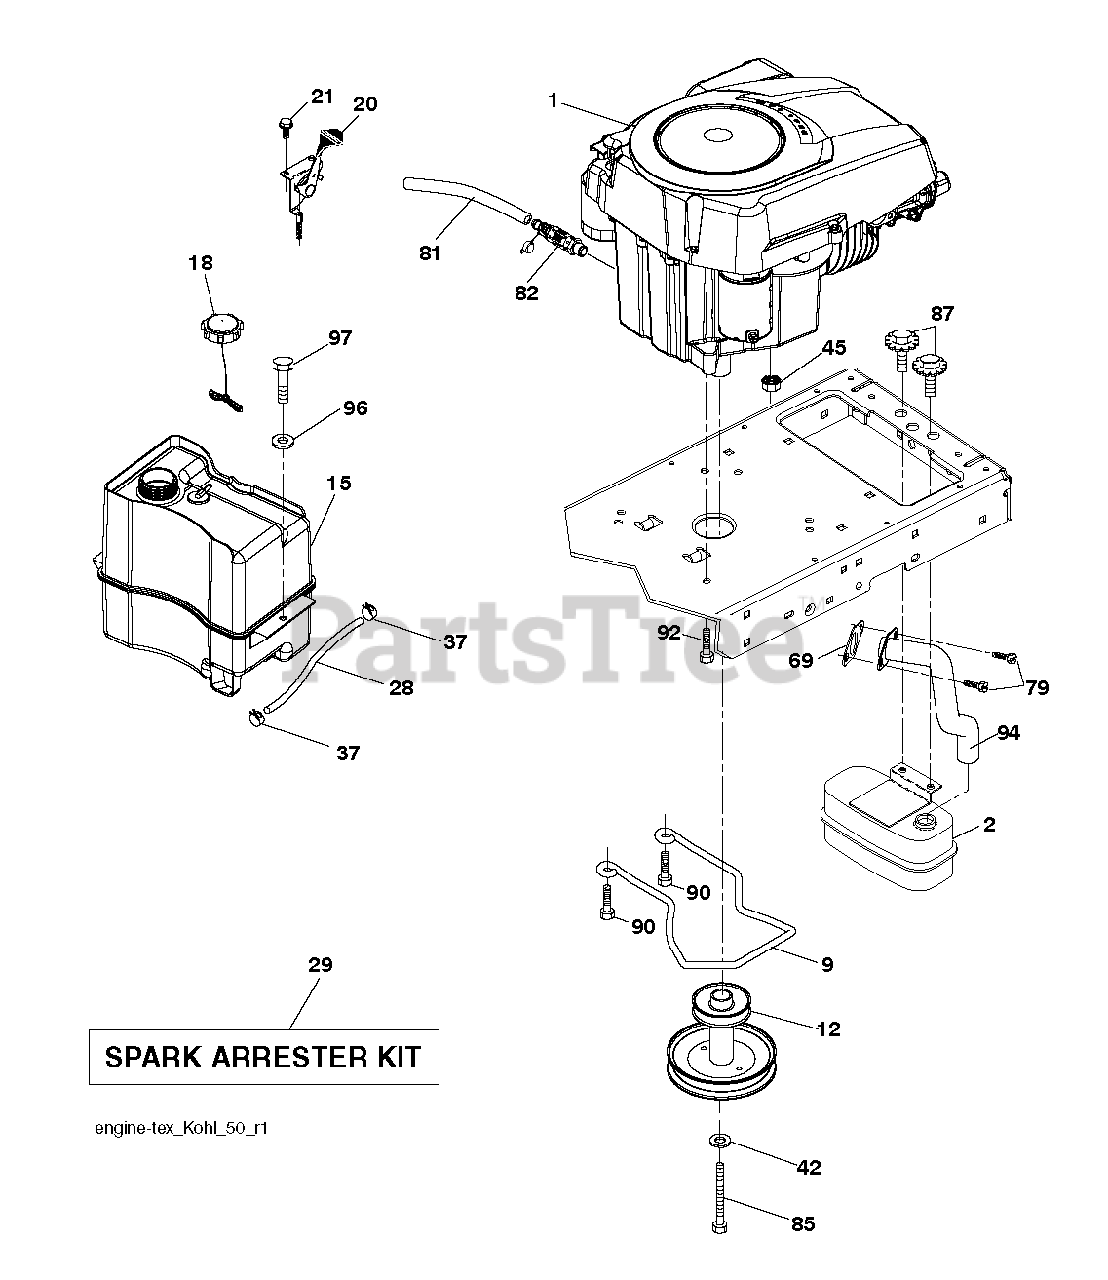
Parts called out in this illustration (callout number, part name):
2	MUFFLER.ASM.SNGL.XTNDED.DFLCTR
9	KEEPER.BELT.ENG.3.25"2BOLT.PNT
12	PULLEY.ENGINE
15	TANK.ASSEMBL.2.5GAL.NON-EPA
18	CAP ASM.FUEL.2.25"FR.
20	CONTROL.TH/CK.COBRA.KO
21	SCREW.#10 X 0.750.BOS
28	LINE.FUEL.20
29	KIT.SPARK ARRESTOR 794945 B&S
37	HOSE CLAMP
42	WASHER 7/16 LOCK
45	NUT
69	GASKET.EXHAUST.KOHLER
79	SCREW.SOCKET HD.5/16-1
81	TUBE, DRAIN OIL ASM.
82	VALUE.OIL.DRAIN
85	BOLT.HEX.7/16-20X4.GR5.1.5BLUE
87	BOLT, 5/16-18 X 1 3/4
90	SCREW 3/8-16X1
92	SCREW 3/8-16X1
94	TUBE.EXHAUST.KOHLER.COURAGE
97	SCREW HEXWSHR 1/4-20X3/4
